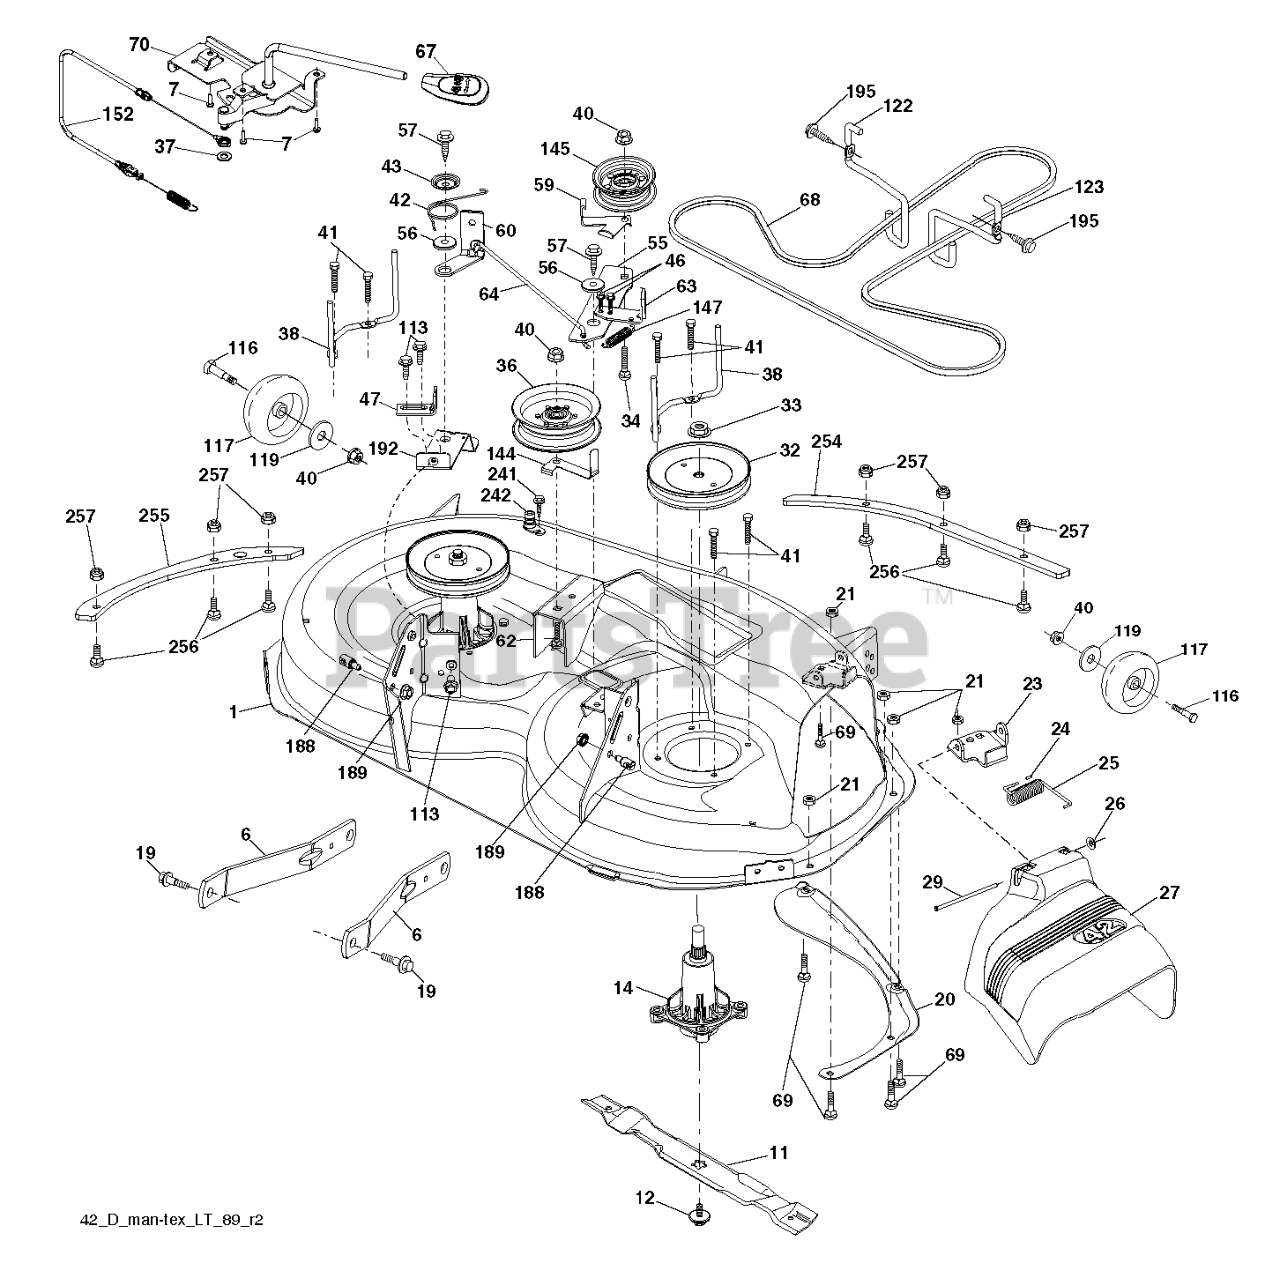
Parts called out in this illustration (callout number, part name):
1	REPAIR KIT KIT.SRV.WLDMENT.42
6	ARM.SUSPENSION.MOWER.R
11	42" HI-LIFT BLADE
12	SCREW.SEMS.7/16-20X1.HEX.HEAD
14	KIT.MANDREL.NONGREASE.TALL
19	BOLT.SHOULDER
20	BAFFLE.VORTEX
23	BRKT.DEFLECTOR.38"2005+
24	CAP-SLEEVE LT
25	SPRING.TORSION.DEFLECT
26	NUT PUSH M
27	SHIELD.DEFLECTOR.MOWER.42"BLAC
32	PULLEY.MANDREL.5.438.PD
34	GSPW Bolts
36	PULLEY.IDLER.2006
37	WASHER
38	KEEPER.BLT.PNT.MNDRL.PULL.6.25
40	NUT LOCK FLG 3/8-16 UNC
41	BOLT.HEX.WASHR.HED.313-18X1.19
42	SPRING.TORSION.BRAKE
43	SRPING.TORSION.RETAINE
46	SCREW.1/4-20X5/8
47	BRKT.CLUTCH.CABLE
55	IDLER.ARM.42"
56	SPACER.RETAINER
57	SCREW 3/8-16X1
59	GUARD, BELT
60	ARM BRAKE MOWER
63	ARM BRAKE MOWER
64	LINKAGE.BRAKE.ASM.ZINC
67	HANDLE.CLUTCH.CABLE.LT
68	BELT.DECK.DRIVE.42"
70	CLUTCH.ASM.MANUAL.YT.PREDATORQ
113	BOLT.5/16HEX.WHS.HD
117	WHEEL.GAUGE.RALLY
122	KEEPER BELT ENGINE LH
123	KEEPER BELT RH
144	KEEPER.BELT.MOWER
145	PULLEY.IDLER.48"PRIMARY
147	RETURN SPRING
152	CABLE.MECHANICAL.CLUTCH
188	STUD.FASTNER.W/ANTI-ROTATE
192	BRKT.BRAKE.STAND.LH.
195	SCREW, 3/8-16X3/4
241	SCREW.TT.#10-32X.5.3/8.FLANGE
242	PORT.WASHOUT
254	PLATES.RENFRC.42DECK.PT431FRNT
255	PLATES.RENFRCE.42DECK.X431SIDE
256	BOLT CUP HEAD SQUARE NECK 1/4-
257	NUT T
